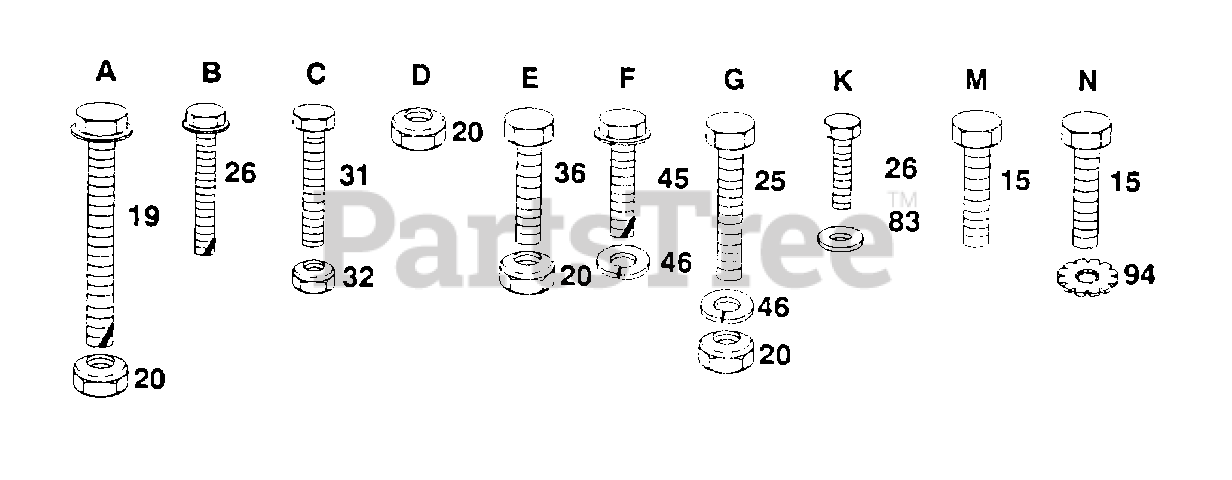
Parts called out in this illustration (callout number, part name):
15	SCREW
19	BOLT
25	BOLT
26	SCREW
31	BOLT
45	SCREW
46	WASHER
83	WASHER
94	LOCKWASHER
